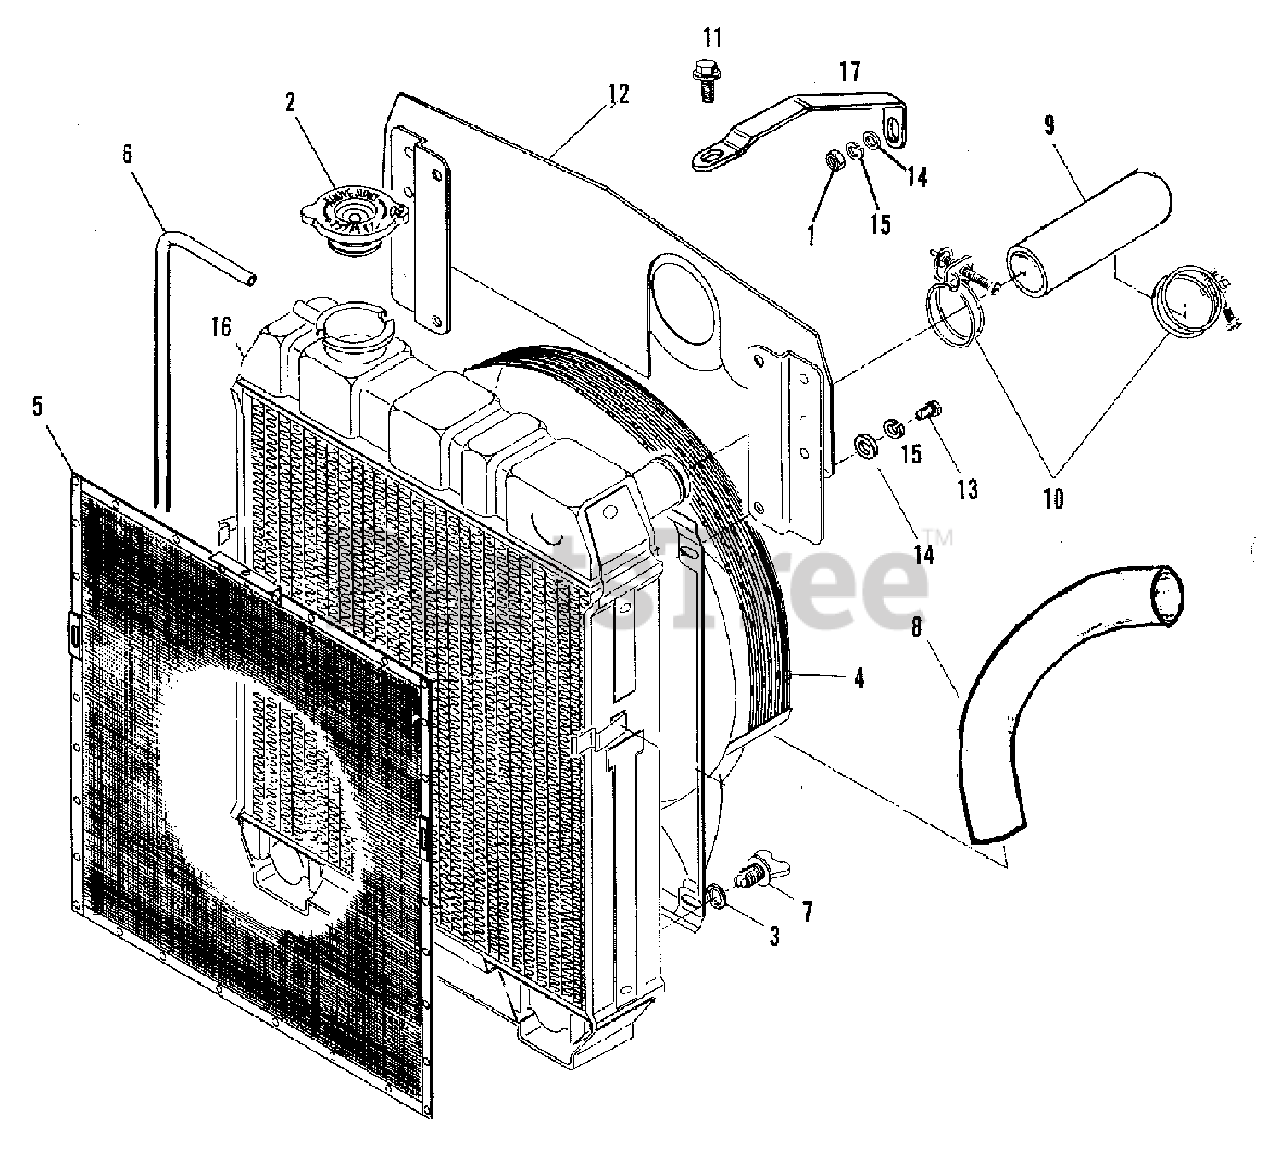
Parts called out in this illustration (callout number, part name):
2	CAP ASSEMBLY
5	PROTECTOR
6	PIPE, vinyl
7	PLUG, water drain (Incl. Item 3)
8	HOSE, lower
9	HOSE, upper
11	CAPSCREW, M8 x 16 w/washer & lockwasher
12	DASHBOARD
13	CAPSCREW, M8 x 16
14	WASHER
15	LOCKWASHER, M8
17	SUPPORT, radiator
